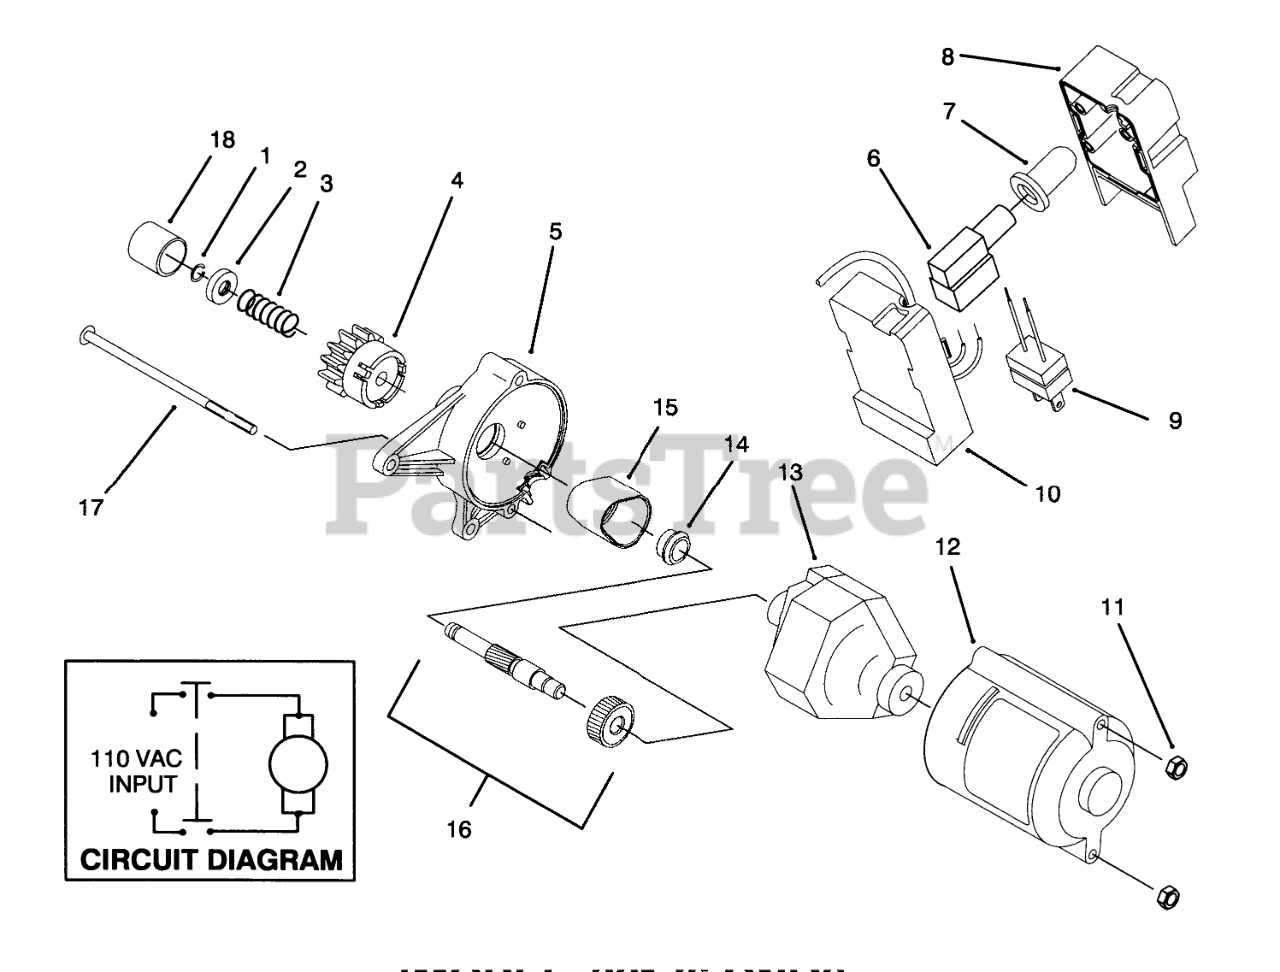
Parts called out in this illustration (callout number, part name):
1	RING-LOCK
2	PINION STOP
3	SPRING
4	PINION ASM
5	Housing-Starter
6	SWITCH-STARTER
7	BOOT-SWITCH
8	Cap-Switch Housing
9	Plug
10	OBS BASE X
11	NUT-LOCK, NI
12	HOUSING COVER
13	Motor
14	BUSHING
15	COVER-GEAR
16	Asm-shaft & Gear
18	CAP-PINION
